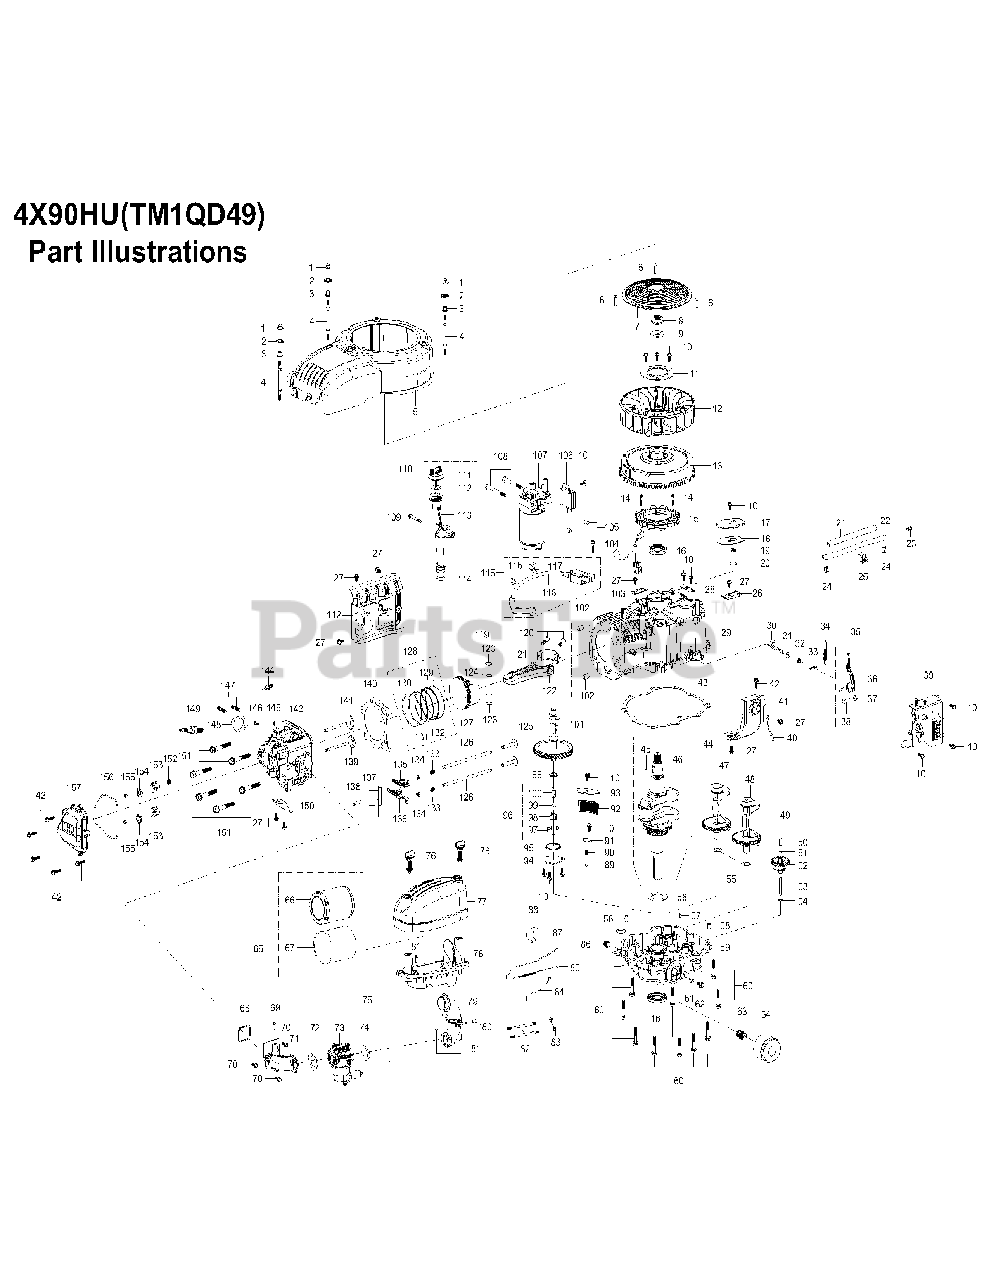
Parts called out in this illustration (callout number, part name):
1	Nut
3	Engine Shroud Spacer
4	Starter / Shroud Stud M6×113
5	Shroud/Air Shield
6	Screw 5.5×25
7	Debris Shield
8	Nut M20×1.5
9	Washer 20.5×5×40
10	Bolt M6×14
11	Vane Plate
12	Cooling Fan
14	Bolt M5×25
15	Charging Coil
16	Oil Seal 38×58×8
17	Breather Cover
18	Gasket, Breather Cover
19	Breather Valve Spring
20	Second Air Vavle
21	Tubing Protective Sieeve
22	Fuel Hose 6.3×12.5×250
24	Clamp, Fuel Hose
25	Wire Clamp
25	Block Asm:Short:X90
26	Wire Plate II
27	Bolt M6×12
29	Crankcase
30	Governor Gear Shaft
31	Washer 8×0.8×16
32	Oil Seal 8×14×4
33	Cotter Pin
34	Governor Spring
35	Governor Lever
36	Governor Arm
37	Governor Arm Nut M6
38	Governor Arm Bolt
39	Governor Gear Bracket Assy
40	Ground Connection
41	Shroud/Right
42	Bolt M6×25
43	Gasket, Crankcase Cover
44	Crankshaft Assembly
45	Woodruff Key
46	Crankshaft
47	Balance Shaft/L
48	Balance Shaft/R
49	Governor Gear Assembly
50	Governor Slide Cap
51	Governor Shaft Stop Ring
52	Governor Gear
53	Governor Shaft
54	Governor Gear Washer
55	Washer 17.2×26×1
56	Washer 38.3×54×1
57	Dowel Pin 7×14
58	Dowel Pin 9×14
59	Crankcase Cover
60	Bolt M8×45
61	Washer 8.3×1.5×17
62	Bolt M8×15
63	Filter Connector Pipe
64	Oil Filter
65	Air Filter Element
66	Paper Filter
67	Sponge Filter
68	Intake Pipe Ring
69	Screw 4.2×20
70	Bolt M6×22
71	Intake Pipe
72	Carburetor Gasket
73	Carburetor
74	Air Filter Gasket
75	Air Filter
76	Air Filter Cover Screw
77	Air Filter Cover
78	Silencer Plate
80	Rubber Cap
81	Screw 4.2×12
82	Stud M6×92
83	Governor Arm Nut M6
84	Choke Lever
85	Idle Spring
86	Drain Bolt
87	Throttle Linkage
88	Venting House
89	Steel Ball 8.731
90	Pressure Release Valve Spring
91	Pressure Release Valve Cover
92	Filter Screen
93	Filter Cover
94	Oil Separater
95	Gasket, Cylinder Head Cover
96	Oil Pump Assembly
97	Oil Pump Outer Shaft Rotator
98	Oil Pump Inner Shaft Rotator
99	Oil Pump Pin
100	Oil Pump Shaft
101	Camshaft
102	Dowel Pin 12×16
103	Wire Plate I
104	Bolt M6×28
105	Dowel Pin 10×12
107	Electric Starter
108	Bolt M8×80
109	Bolt M6×45
110	Dipstick Assembly
111	Dipstick Cover
112	Upper O-Ring
113	Dipstick Seat
114	Lower O-Ring
115	Ignition Coil Assembly
116	Vibration Pad
117	Wire Clamp
118	Ignition Coil
119	Connecting Rod
120	Connecting Rod Bolt
121	Connecting Rod Cap
122	Connecting Rod
123	Circlip, Piston Pin
124	Piston Pin
125	Tappet
128	Piston Ring Set
129	Scraper Ring, Oil Ring
130	1st Piston Ring
131	2nd Piston Ring
132	Lining Ring, Oil Ring
133	Valve Clearance Adjustment Screws Combination
135	Rocker Arm
136	Rocker Arm
137	Rocker Arm Core Shaft
138	Rocker Arm Core Shaft Bolt
139	Exhaust Valve
140	Gasket, Cylinder Head
140	Head Asm Cyl:X90
141	Intake Vavle
142	Shroud/Lift
143	Cylinder Head
145	Washer 5.3×1×10
146	Bolt M5×10
148	Gasket, Muffler
149	Spark Plug(F6Rtc)
151	Bolt M10×1.25×70
152	Intake Valve Seal
153	Valve Spring
154	Valve Spring Seat
155	Valve Cap
156	Valve Cover Ring
157	Cylinder Head Cover
